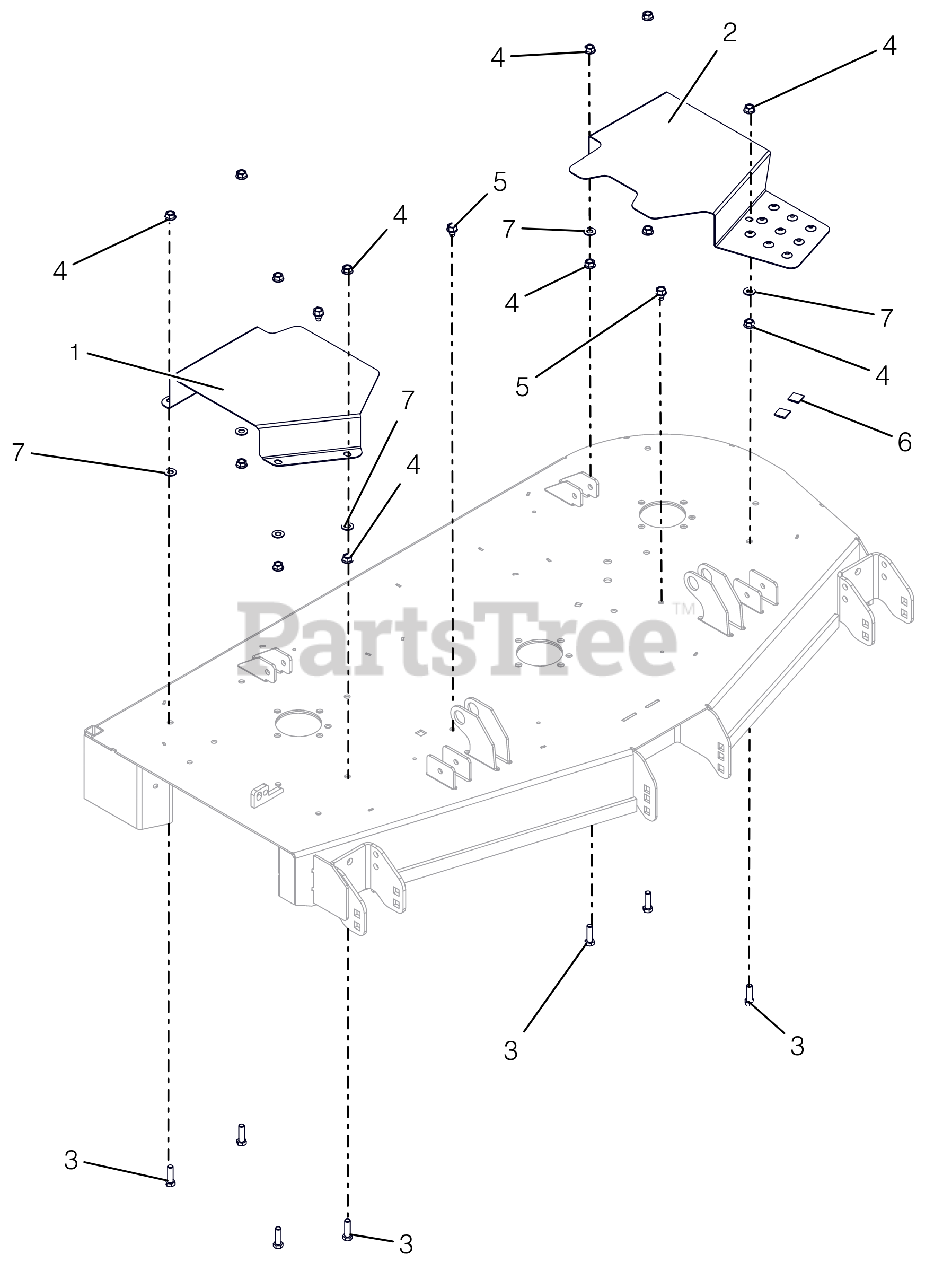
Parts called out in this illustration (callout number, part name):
1	COVER, BELT 52" & 60" RIGHT
2	COVER, BELT 52" LEFT
3	@BLT-HEX .38-16X1.25 GR5 YWZC
4	@NUT-SPNLK-FLG .375-16 YWZC
5	@SCR-TAP .38-16X.50 HWH TR YWZ
7	@WSHR-FL-STL.406X.812X.065 YWZ
